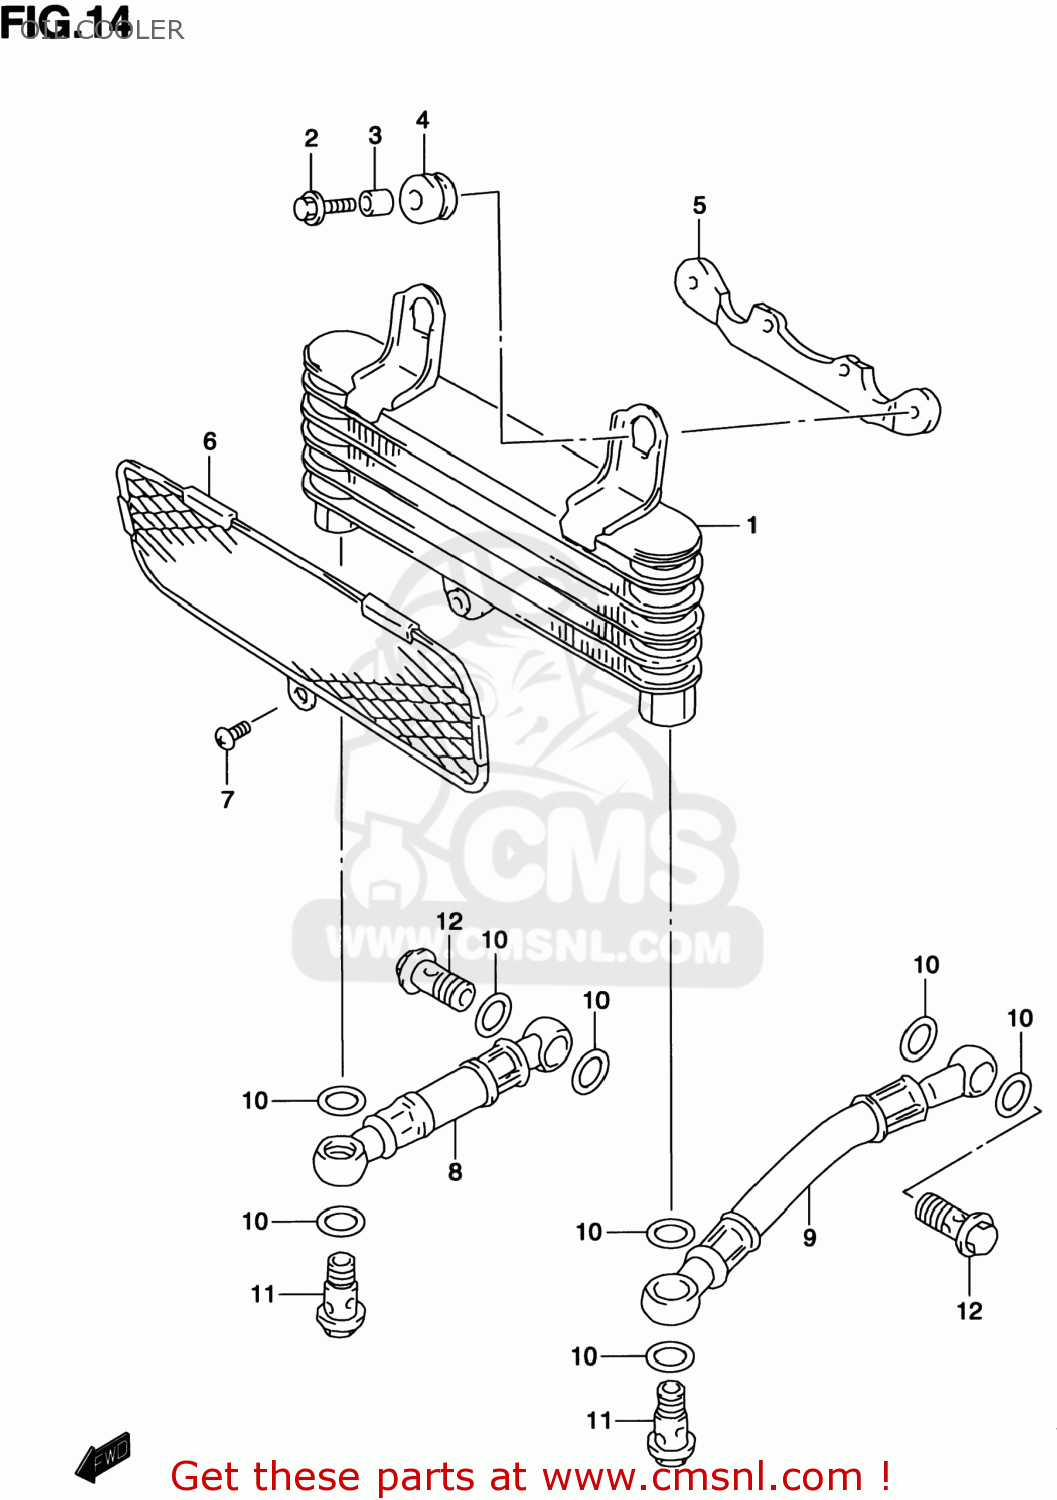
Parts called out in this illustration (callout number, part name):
1	COOLER ASSEMBLY,OIL
2	BOLT 6X20
3	SPACER(6.5X10X10)
4	CUSHION
5	BRACKET,OIL COOLER
6	GUARD,OIL COOLER
7	SCREW
8	HOSE,OIL COOLER,R
9	HOSE COMP,OIL COOLER,LEFT
10	GASKET(14X20X1.5) (NAS)
11	BOLT UNION
12	BOLT UNION
